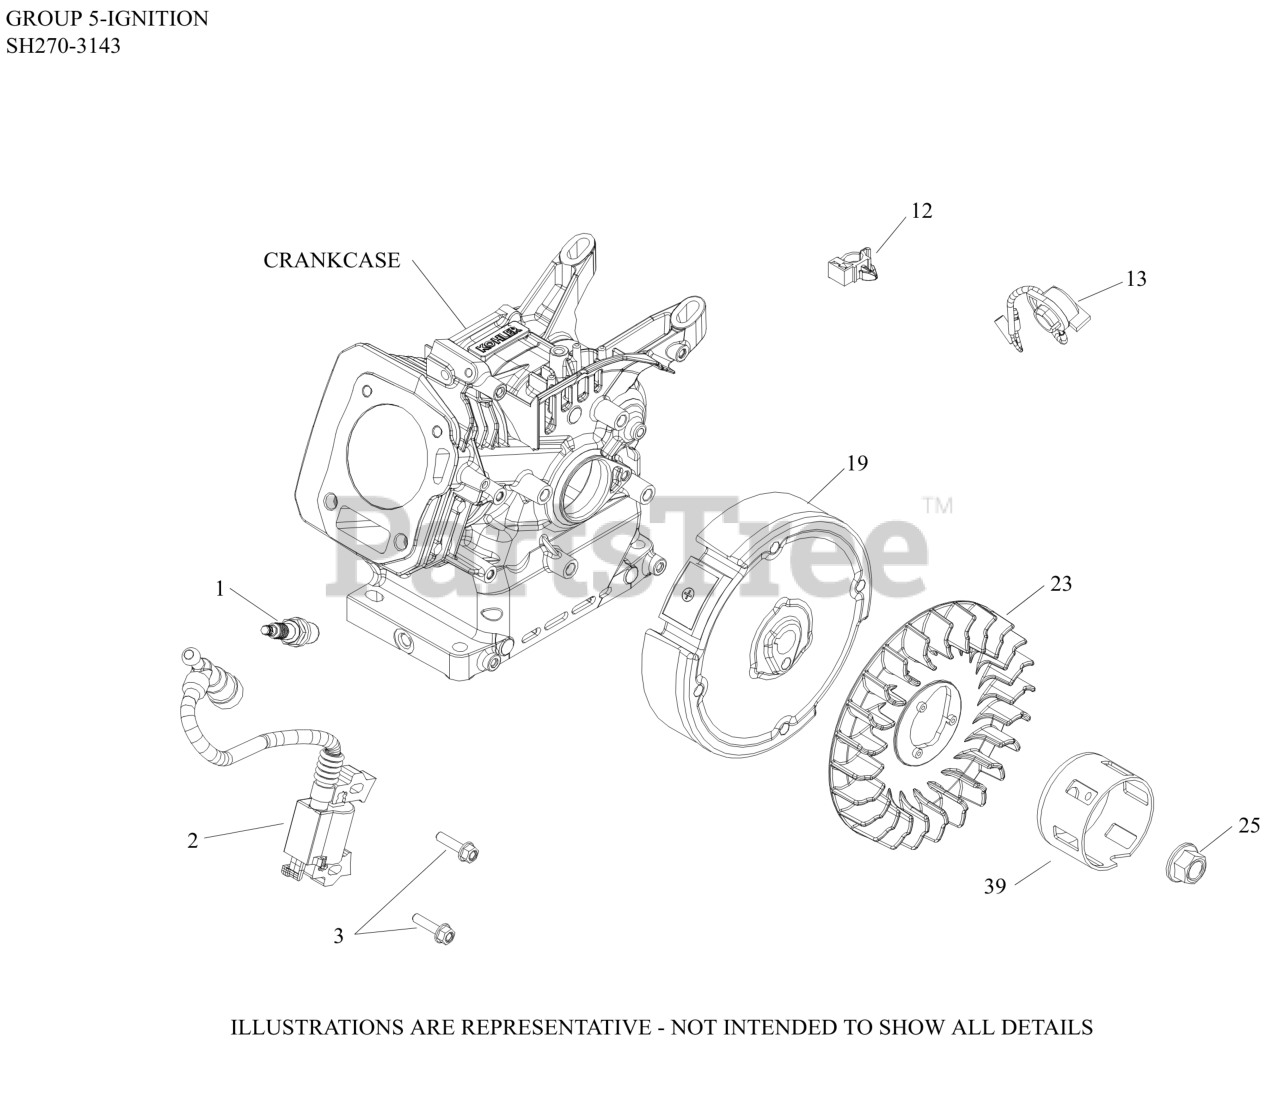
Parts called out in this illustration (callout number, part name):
1	SPARK PLUG
2	MODULE, IGNITION
3	SCREW, M6 X 25-(#25086436S)
9	LEAD, GROUND TO KILL
12	CLIP, WIRE HARNESS
13	SWITCH, IGNITION
19	FLYWHEEL ASSEMBLY
23	FAN, FLYWHEEL
25	NUT, FLYWHEEL (W/SERRATIONS)
39	STARTER CUP
